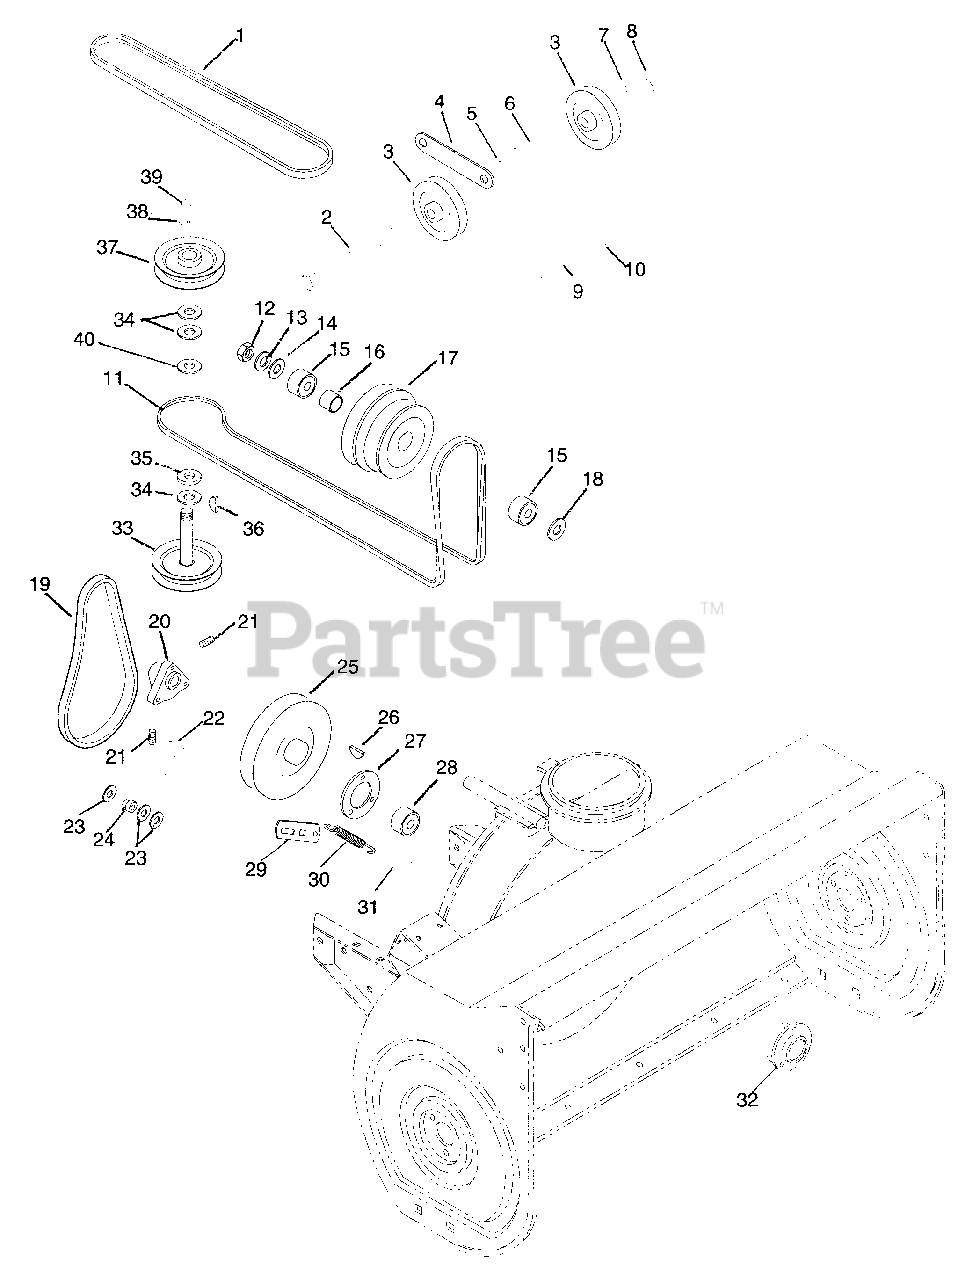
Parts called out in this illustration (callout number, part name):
2	BLT-HEX .38-16X5.00 PL GR2
3	IDLER-V 4.00 X .38 NWHAMSHR
4	STRAP
5	WSHR-FL-STL .754X1.000X.032
6	IDLER BRACKET
7	WSHR-LK .375X.115 HVY PL
8	NUT-HEX .375-16
9	CLEVIS PIN 3/8X3.0 YWZC
10	PIN-HAIR INT .08X.38X1.42 YWZC
11	V-BELT, HA-WRAPPED
12	NUT-JAM .75-10 PL
13	WSHR-LK-INT .750X.050 MED
14	WSHR-FL-STL .781X1.250X.059 PL
15	BRG-BALL .750X1.781X.61
16	SPACER 1.00 X .770/.760 X .813
17	SHEAVE, DOUBLE
18	WSHR-FL-STL .781X1.500X.188
19	V-BELT, 4L-RAW EDGE
21	SCR-SET .32-18X.50 SKHCUP OH
22	IDLER
23	WSHR-FL-STL .505X.880X.072 PL
24	SPACER -FLANGED .390X.500X.781
25	PLY-V 9.0 X 1.25 3BLT
26	KEY-WDRF .188X.875X.375 SAE11
27	BEARING FLANGE
28	BRG-BALL1.0X2.0X.56
29	IDLER ARM
30	SG-TENS .090X.75X3.50 WLD 34
31	BLT-RDHDSQNK .38-16X1.50 PL
32	BEARING FLANGE
33	SPINDLE SHAFT
34	WSHR-FL-STL .755X1.375X.125
35	SPACER .755X1.250X.370
36	KEY-WDRF .188X.75X.313 SAE 9
37	PLY-V 4.50 X .75 W/KEY SALEM
38	WSHR-LK-INT .750X.050 MED
39	NUT-JAM .75-10 PL
40	WSHR-FL-STL .755X1.375X.125
